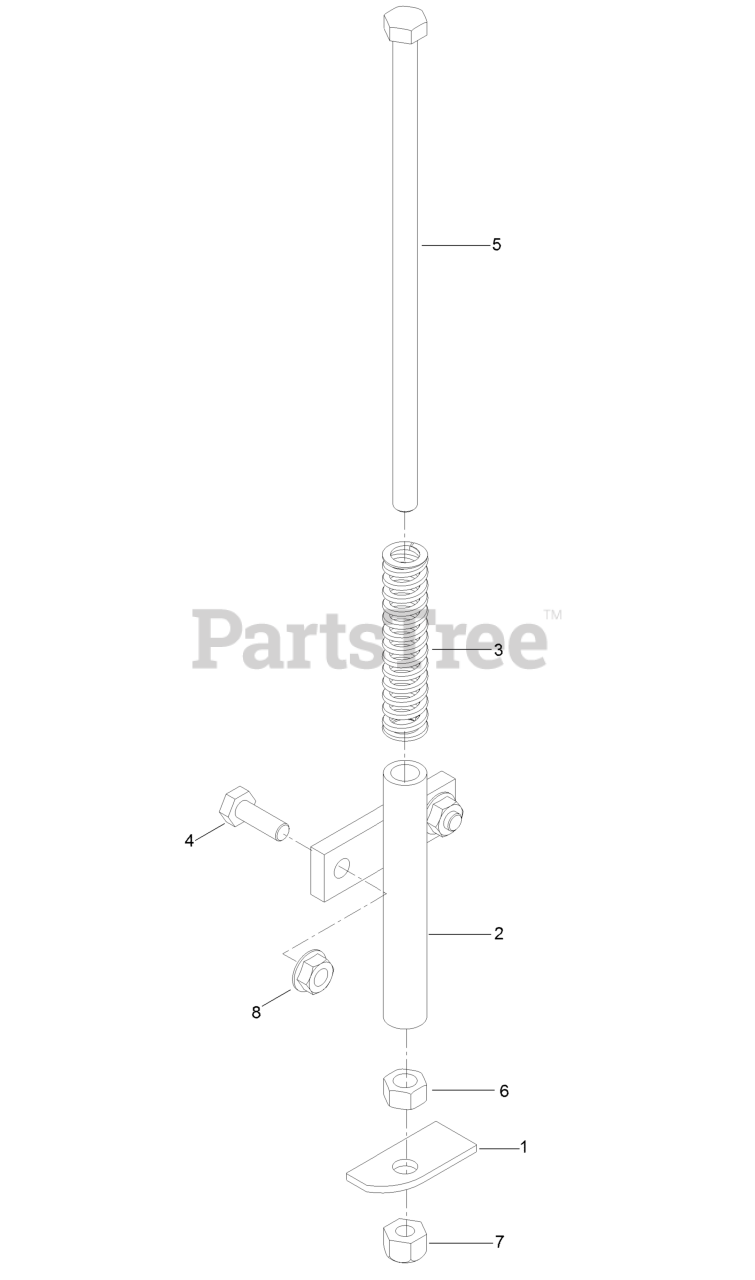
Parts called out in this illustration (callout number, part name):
1	Plate-Switch
2	Mount-Spring, Seat
3	Spring-Switch, Seat
4	Screw-HH
5	Screw-HH
6	Nut-Hex
7	Nut-Lock, NI
